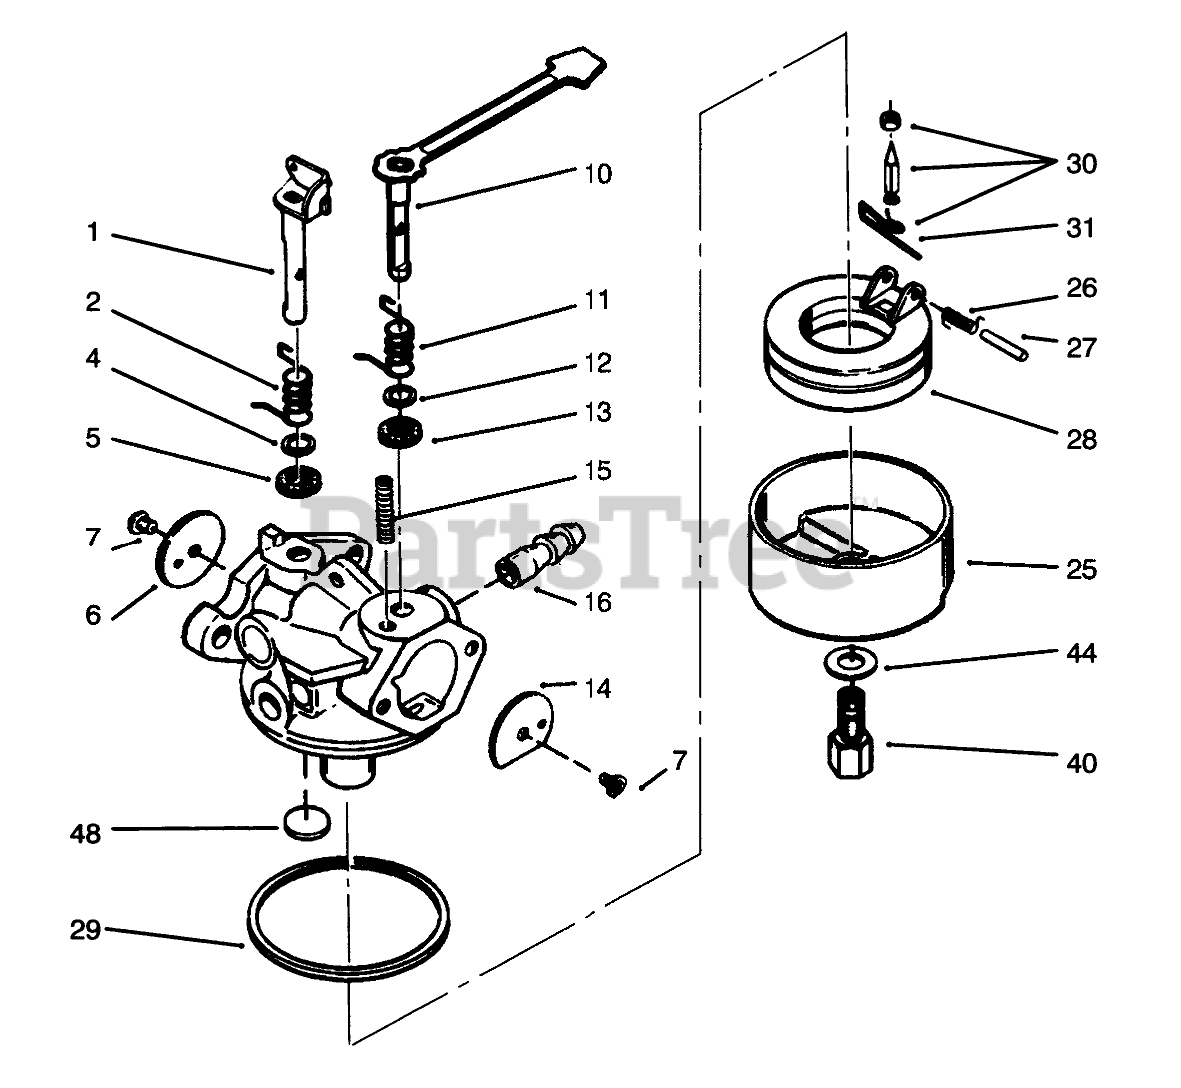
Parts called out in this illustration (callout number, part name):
1	Throttle Shaft & Lever Asm.
2	Spring-Trottle, Return
4	Washer-Seal, Dust
5	Seal-Dust
6	Shutter-Throttle
7	Screw-Shutter
10	Choke Shaft and Lever ASM
14	Shutter-choke
15	Spring-Positioning, Choke
16	Fitting-Fuel
25	Bowl Float
26	Spring-Float, Dampening
27	Shaft-Float
28	Float
29	O Ring-Bowl, Float
30	Inlet Needle, Seat & Clip (Incl. ref. #31)
31	Clip-Spring
40	Nut-Float Bowl
44	Gasket-Bowl
48	Plug-Welch, Atmospheric Vent
